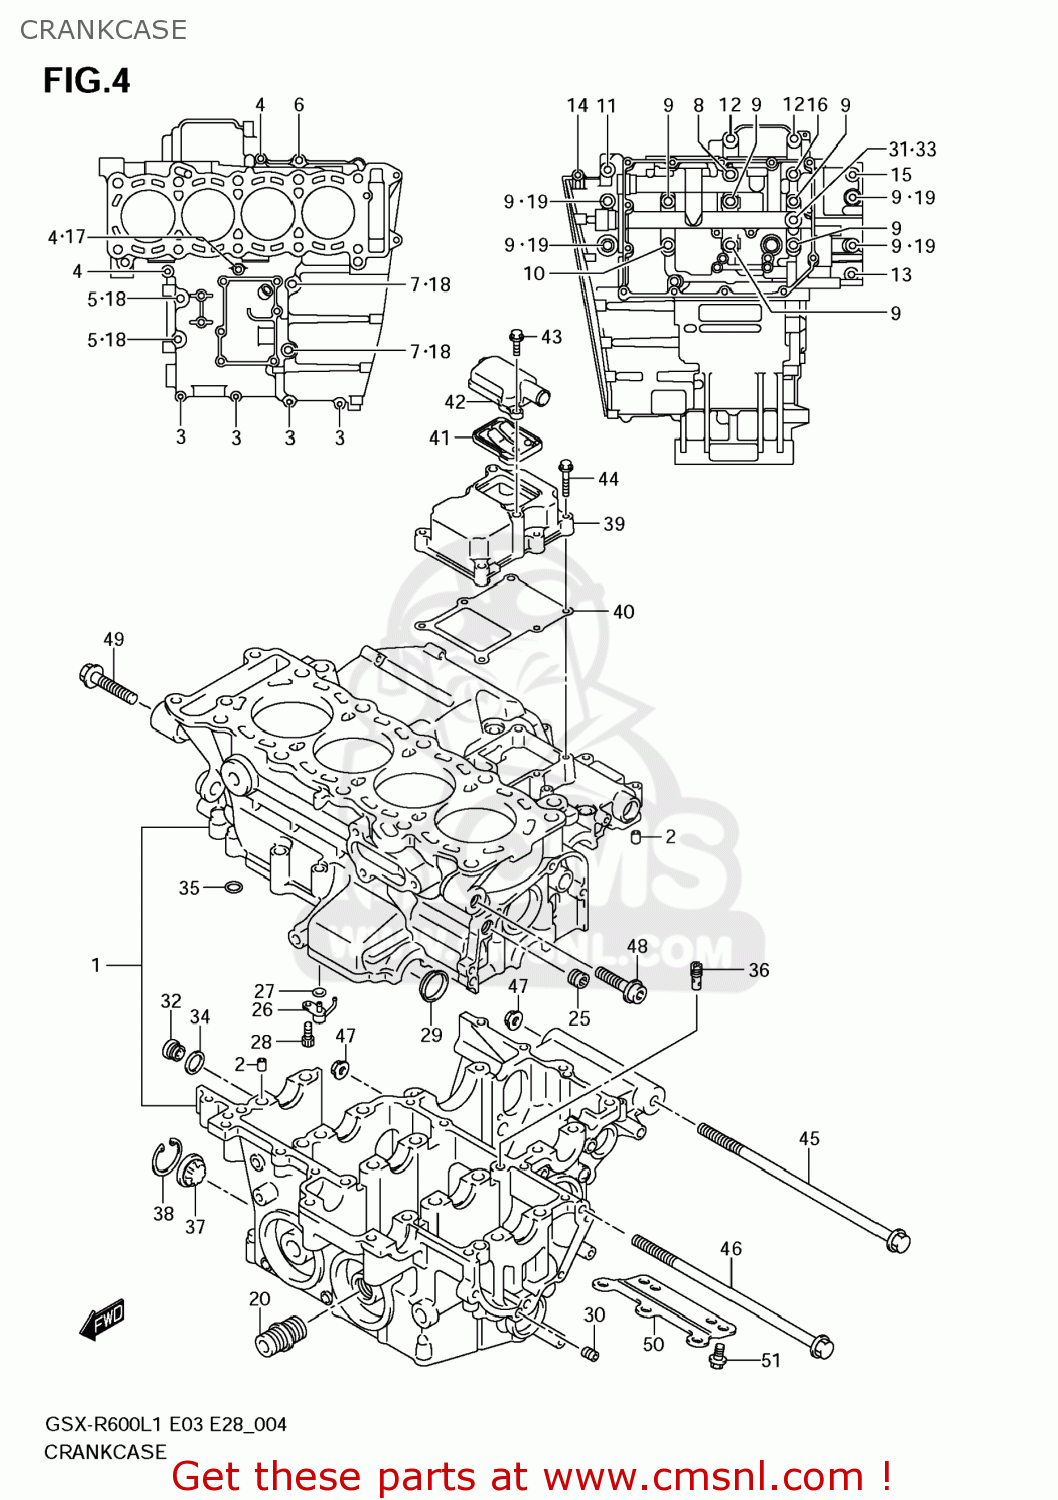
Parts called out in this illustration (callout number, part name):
1	CRANKCASE SET
2	PIN,CRANKCASE
3	BOLT
4	BOLT
5	BOLT
6	BOLT
7	BOLT
8	BOLT(8X105)
9	BOLT(9X95)
10	BOLT(9X80)
11	BOLT
12	BOLT(8X55)
13	BOLT
14	BOLT
15	BOLT
16	BOLT
17	GASKET(5.8X13X1.2) (NAS)
18	GASKET(8.2X14X1) (NAS)
19	GASKET(10.2X20X2).3 (NAS)
20	UNION,OIL STAND
21	O RING(D:1.9,ID:99.5)
22	BOLT(6X20)
23	BEARING,CRANK THRUST(GREEN)
24	BEARING,CRANK THRUST(RED)
25	JET,OIL GALLERY(3.6)
26	JET,PISTON COOLING
27	O RING(D:1.2,ID:4)
28	BOLT(6X12)
29	PLUG
30	PLUG(1/8PT,H:5.5)
31	PLUG(L:12)
32	PLUG
33	GASKET(12.1X16.2X3.7) (NAS)
34	GASKET(16X22X2) (NAS)
35	O RING(D:1.9,ID:7.8)
36	JET(140)
37	LENS,OIL LEVEL CHECK
38	CIRCLIP
39	COVER,BREATHER
40	GASKET,BREATHER COVER (NAS)
41	VALVE ASSY,BRE
42	COVER,BREATHER REED VALVE
43	BOLT
44	BOLT
45	BOLT(10X215)
46	BOLT(10X205)
47	NUT
48	BOLT(10X45)
49	BOLT(10X55)
50	PLATE,CRANKCASE LWR
51	BOLT(6X10)
